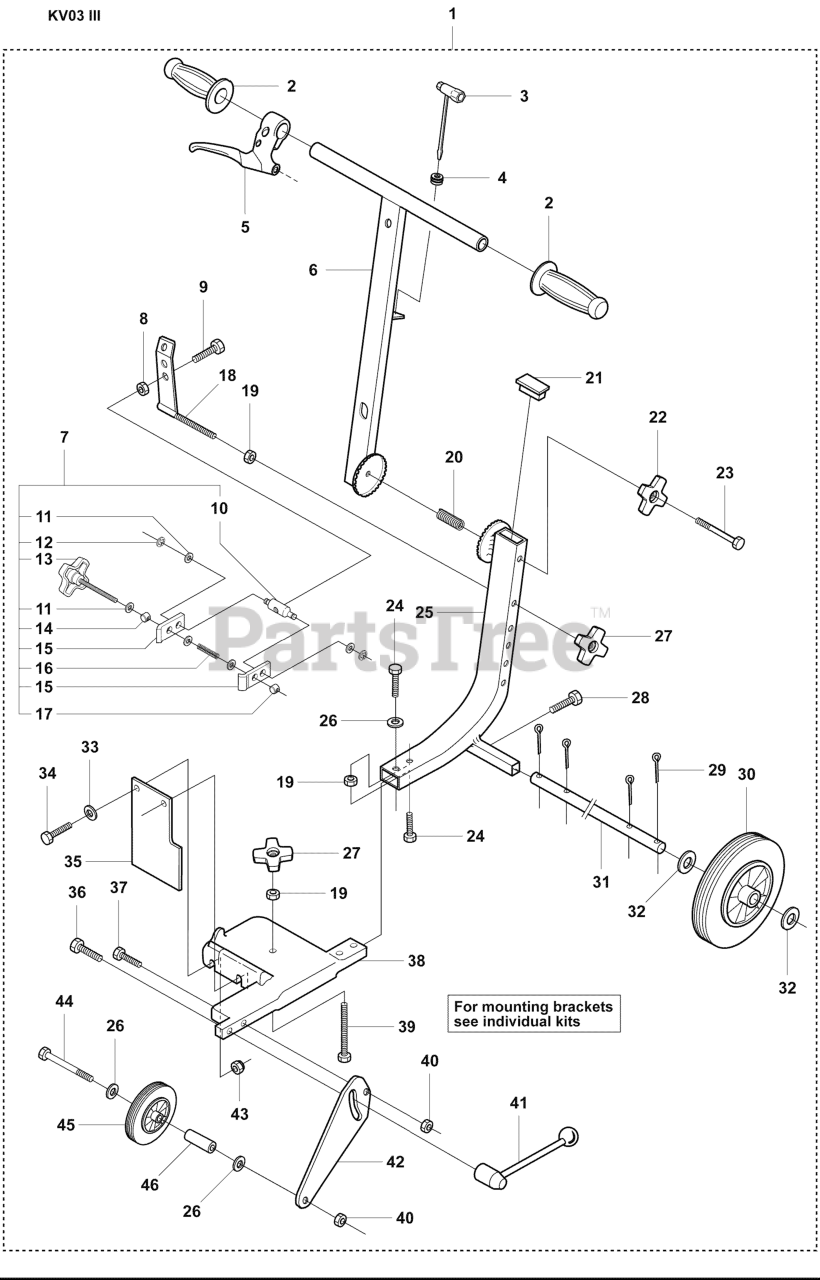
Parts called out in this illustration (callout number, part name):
1	CUTTING TROLLEY
4	ANTIVIBE ELEMENT
5	HANDLE-TRIGGER
7	BRACKET
8	NUT
11	WASHER - M6
13	STEERING WHEEL
19	NUT
20	COMPRESSION SPRING
22	STEERING WHEEL
25	FRAME WELDMENT
26	WASHER - 25X8.5X2.3
28	SCREW 8X20
35	SPRAY GUARD
38	COUNTERWEIGHT
40	LOCKNUT M8
44	SCREW M8 X 70
46	SPACING SLEEVE
